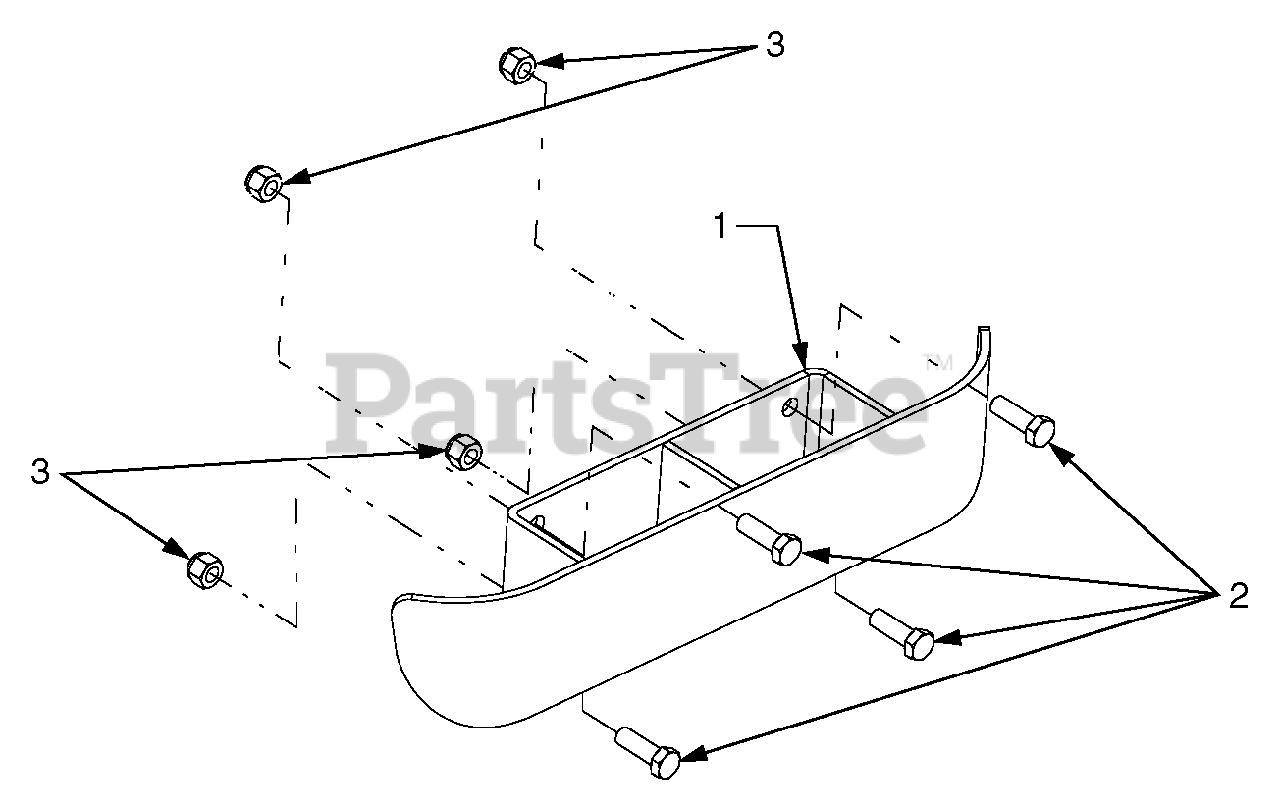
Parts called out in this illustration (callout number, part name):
1	Weight Bracket/Bumper Ass'y.
2	Screw, Hex Cap, 1/2-13 x 1.5 GR5
3	Nut, Hex Insert Lock, 1/2-13 GR8
